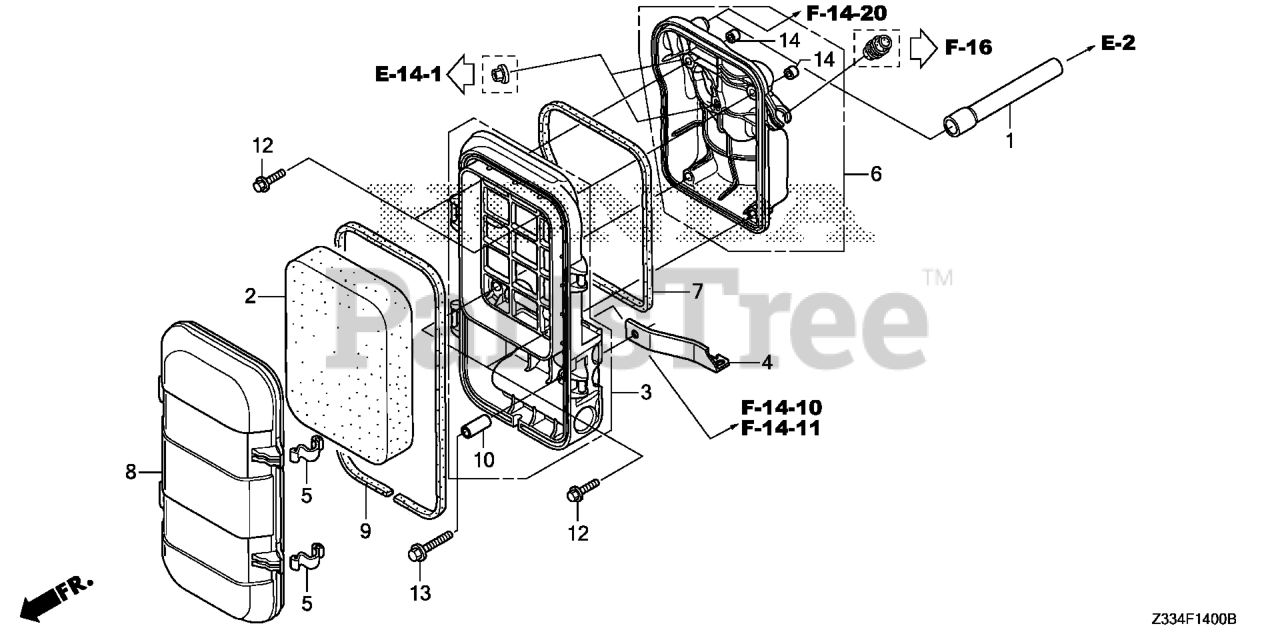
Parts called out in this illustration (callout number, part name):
1	TUBE, BREATHER
2	ELEMENT, AIR CLEANER
3	HOUSING, AIR CLEANER
4	STAY, AIR CLEANER
5	SPRING, AIR CLEANER HOUSING LID
6	BASE, AIR CLEANER
7	SEAL, AIR CLEANER HOUSING
8	COVER, AIR CLEANER
9	SEAL, AIR CLEANER COVER
10	COLLAR, AIR CLEANER
12	BOLT, FLANGE (5X18)
13	BOLT, FLANGE (6X32)
14	COLLAR, AIR CLEANER
